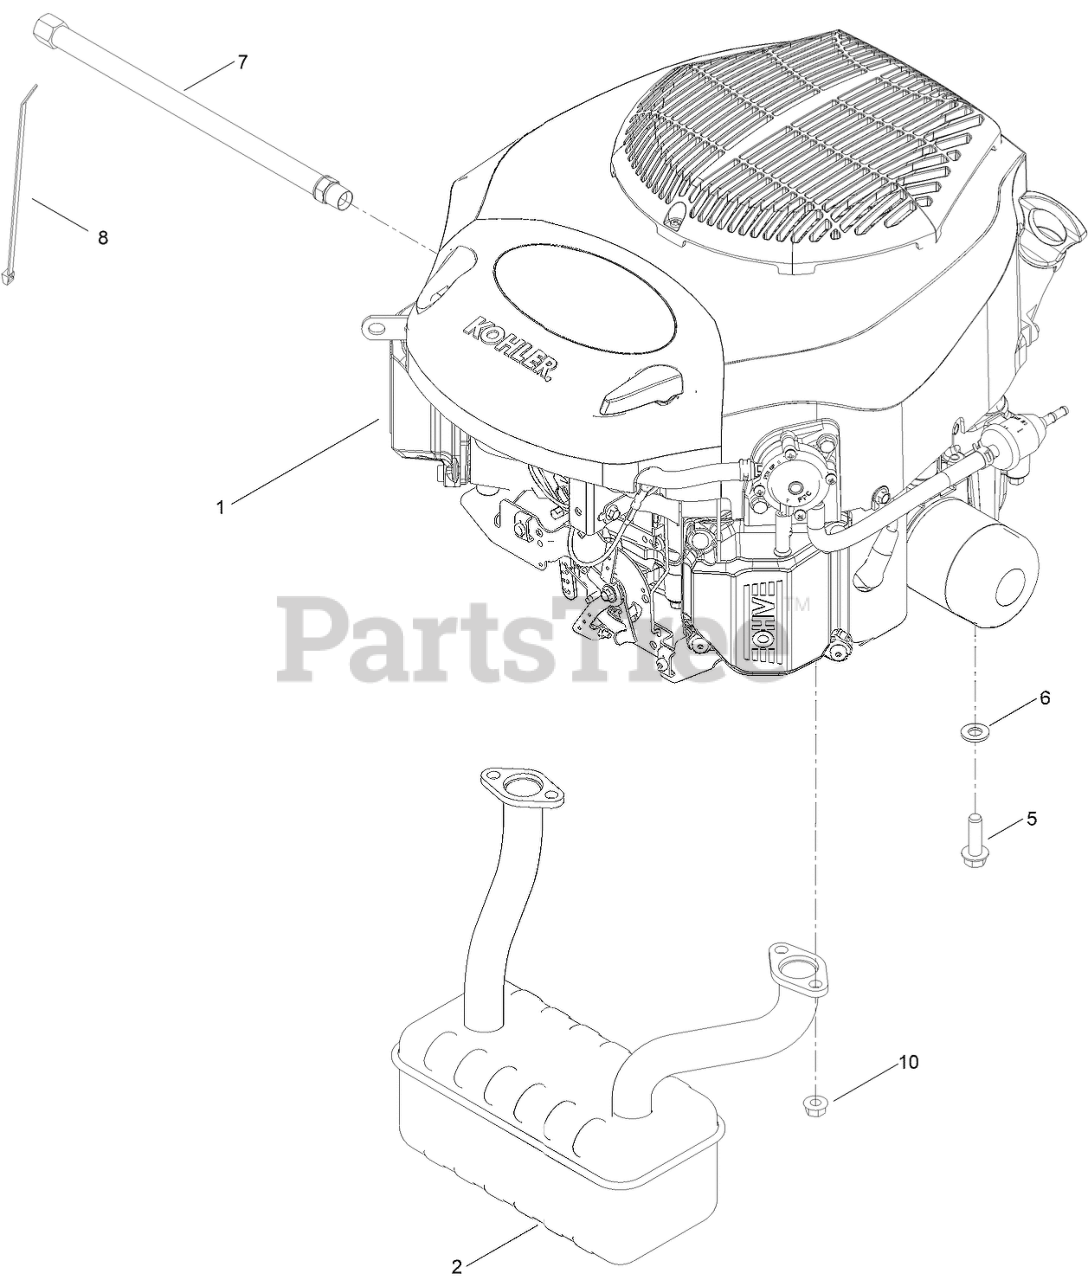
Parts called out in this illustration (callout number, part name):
1	ENGINE-KOHLER, KT725 LOW SPEED
2	MUFFLER
5	SCREW-HWH, THD ROLL
6	WASHER-FLAT
7	HOSE-DRAIN, OIL
8	TIE-CABLE
10	NUT-HF
